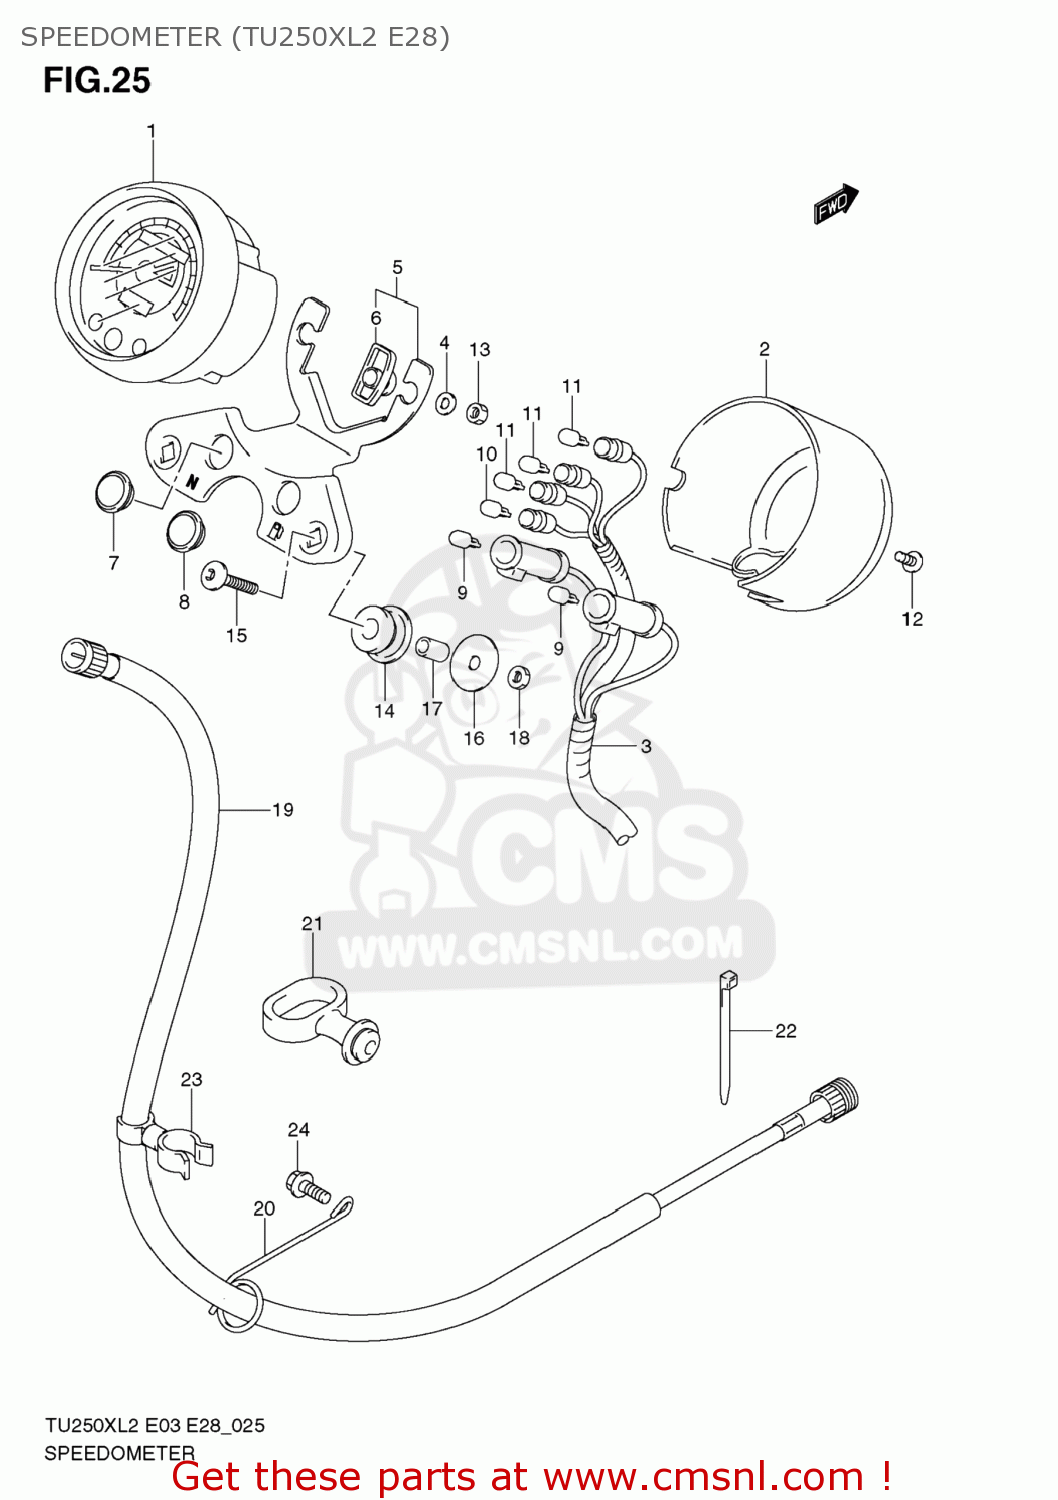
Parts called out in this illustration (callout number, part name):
1	SPEEDOMETER
2	COVER
3	CORD ASSY
4	WASHER(5.2X16X1)
5	BRACKET ASSY
6	CUSHION,DAMPER
7	LENS(GREEN)
8	LENS(ORANGE)
9	BULB(12V3.4W,T10)
10	BULB(12V3W,T6.5)
11	BULB(12V1.7W,T6.5)
12	SCREW
13	NUT
14	CUSHION,METER BRACKET
15	BOLT(6X30)
16	WASHER(6.5X28X1.6)
17	SPACER(6.5X10X15.7)
18	NUT
19	CABLE ASSY,SPEEDOMETER
20	GUIDE,SPEEDOMETER CABLE
21	GUIDE,CABLE
22	CLAMP(L:145)
23	CLIP
24	BOLT
